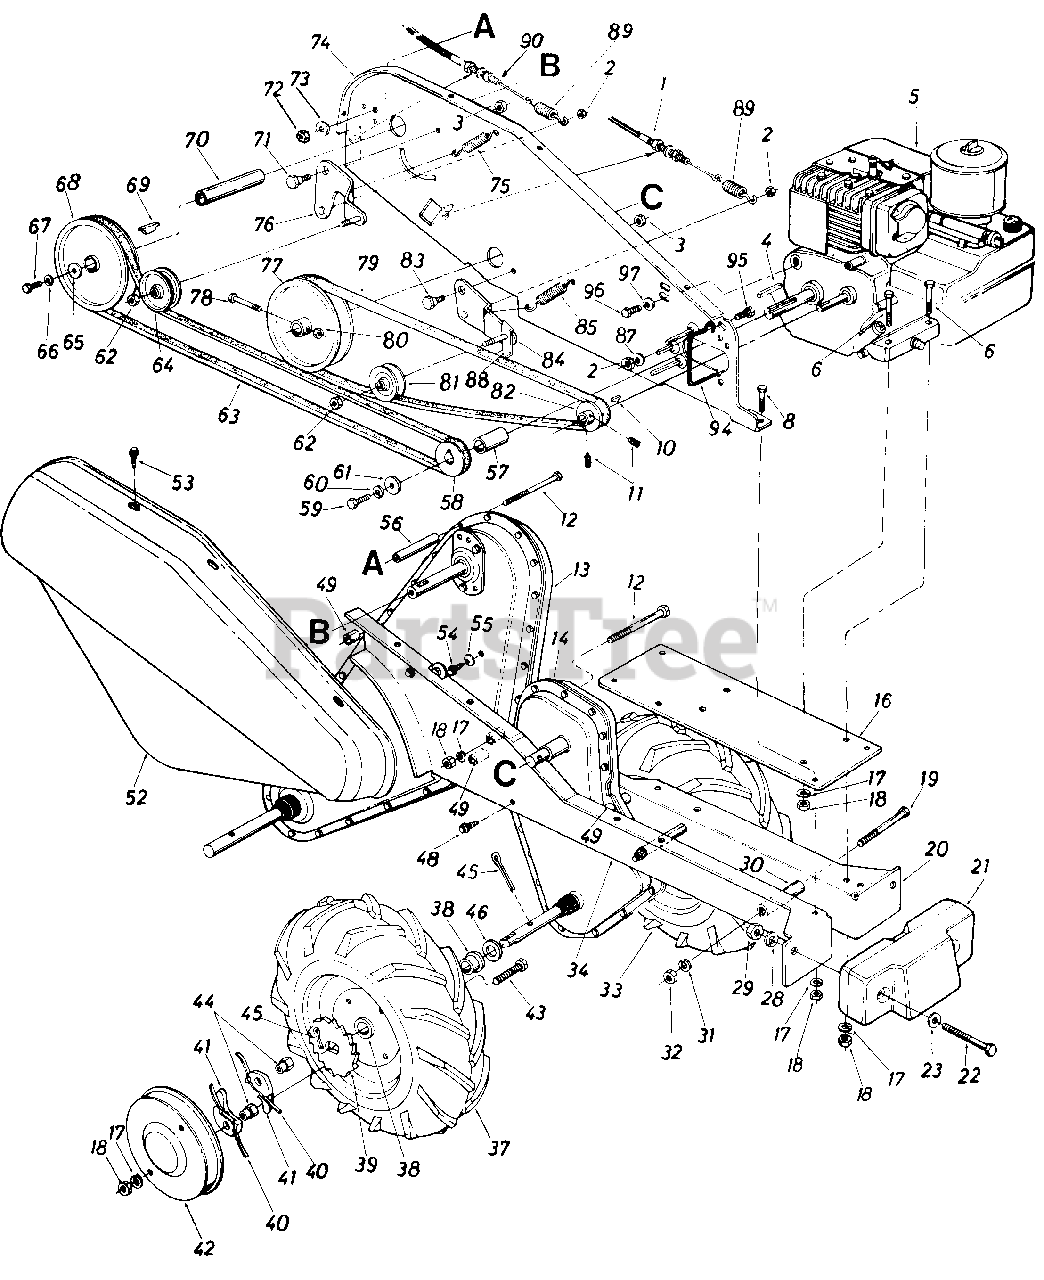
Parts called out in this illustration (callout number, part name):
1	Clutch Control Cable
2	Hex Cent. L-Nut 1/4-20 Thd.
3	Hex Cent. L-Nut 3/8-16 Thd.
4	Sq. Key 3116" Dia. x .75
6	Hex Bolt 5/16-18 x 1.50" Lg.
8	Hex Bolt 5/16-18 x .75" Lg.
10	Hi-Pro Key #5 Woodruff
11	Set Scr. 1/4-28 x .25" Lg.
12	Hex Bolt 5/16-18 x 3.0" Lg.*
18	Hex Nut 5/16-18 Thd.*
19	Hex Bolt 3/8-24 x 3.0" Lg.
22	Hex Bolt 1/2-13 x 4.0" Lg.
23	Fl-Wash. 1/2" I.D. x 1.0" O.D.
28	L-Wash. 1/2" I.D.
29	Hex Nut 1/2-13 Thd.
30	Spacer 3/8 I.D. x 5/8" O.D. x 2.18" Lg.
31	L-Wash. 3/8 I.D.
32	Hex Nut 3/8-24 Thd.
33	Comp. Wheel Ass'y. L.H.
38	Flange Brg. 7/8" I.D. x 1.i2" Lg.
39	Ratchet Wheel
40	Nylon Spring
41	Pawl .44" I.D.
42	Wheel Cover
43	Hex Bolt 5/16-18 x 1.25" Lg.
44	Special Hex Nut 5/16-24 Thd.
45	Cotter Pin 118" Dia. x 1.25" Lg.*
46	Fl-Wash. 7/8" I.D. x 1-3/8 O.D. x .06
48	Hex Wash. Self-Tap Scr. 5/16-24 x .50" Lg.
49	Spacer 5/16" I.D. x 16 Ga. x .96" Lg.
52	Belt Cover
53	Hex Wash. S-Tap Scr. 1/4-20 x .50" Lg.
54	Hex Wash. S-Tap Scr. 1/4-20 x 3/8" Lg.
55	Bell-Wash. 1/4" I.D.
56	Spacer 3/8 I.D. x 1/2" O.D. x 2.0" Lg.
57	Spacer 3/4" I.D. x 1.12" O.D. x 1.56" Lg.
58	1/2" "V"-4L Pulley 314" I.D. x 2.59" O.D.
59	Hex Bolt 3/8-24 x 1.00" Lg.
60	L-Wash. 3/8 I.D.
61	Fl-Wash. 3/8 I.D. x 1.25" O.D.
62	Hex L-Nut 3/8-24 Thd.
63	"V"-Belt 1/2" x 54" Lg.
64	Fl-Idler Pulley 3.75" O.D. x 3/8 I.D.
65	Fl-Wash. .25" I.D. x .93" O.D. x .1 20
66	L-Wash. 1/4" I.D.
67	Hex Bolt 1/4-28 x .75" Lg.
68	Split Pulley 6" Dia. x 5/8" I.D.
69	Hi-Pro Key
70	Spacer
71	Shld. Bolt 1/2" Dia. x .210" Lg.
72	Hex Nut 5/16-18 Thd.
73	L-Wash. 5/16" I.D.
74	Side Plate Ass'y.
75	Ext. Spring .50" O.D. x 1.55" Lg.
76	Idler Bracket Ass'y. Tines
77	Pulley 6" Dia. x 5/8" I.D.
78	Hex Bolt 1/4-28 x 1.50" Lg.
79	"V"-Belt 1/2" x 43" Lg.
80	Hex Cent. L-Nut 1/4-28 Thd.
81	"V"-Idler Pulley 2-5/8" O.D.
82	1/2" "V"-Pulley 21/4" O.D. x .50" I.D.
83	Shld. Bolt 1/2" Dia. x .160" Lg.
84	Idler Bracket Ass'y Wheels
85	Ext. Spring .50" O.D. x 1.55" Lg.
87	Bell-Wash. 1/4" I.D.
88	Belt Keeper Ass'y.
89	Ext. Spring
90	Clutch Control Cable
94	Belt Keeper
95	Hex Bolt 1/4-20 x 1.25" Lg.
96	Hex Bolt 5/16-24 x .62" Lg.
97	Bell-Wash. 5/16" I.D.
